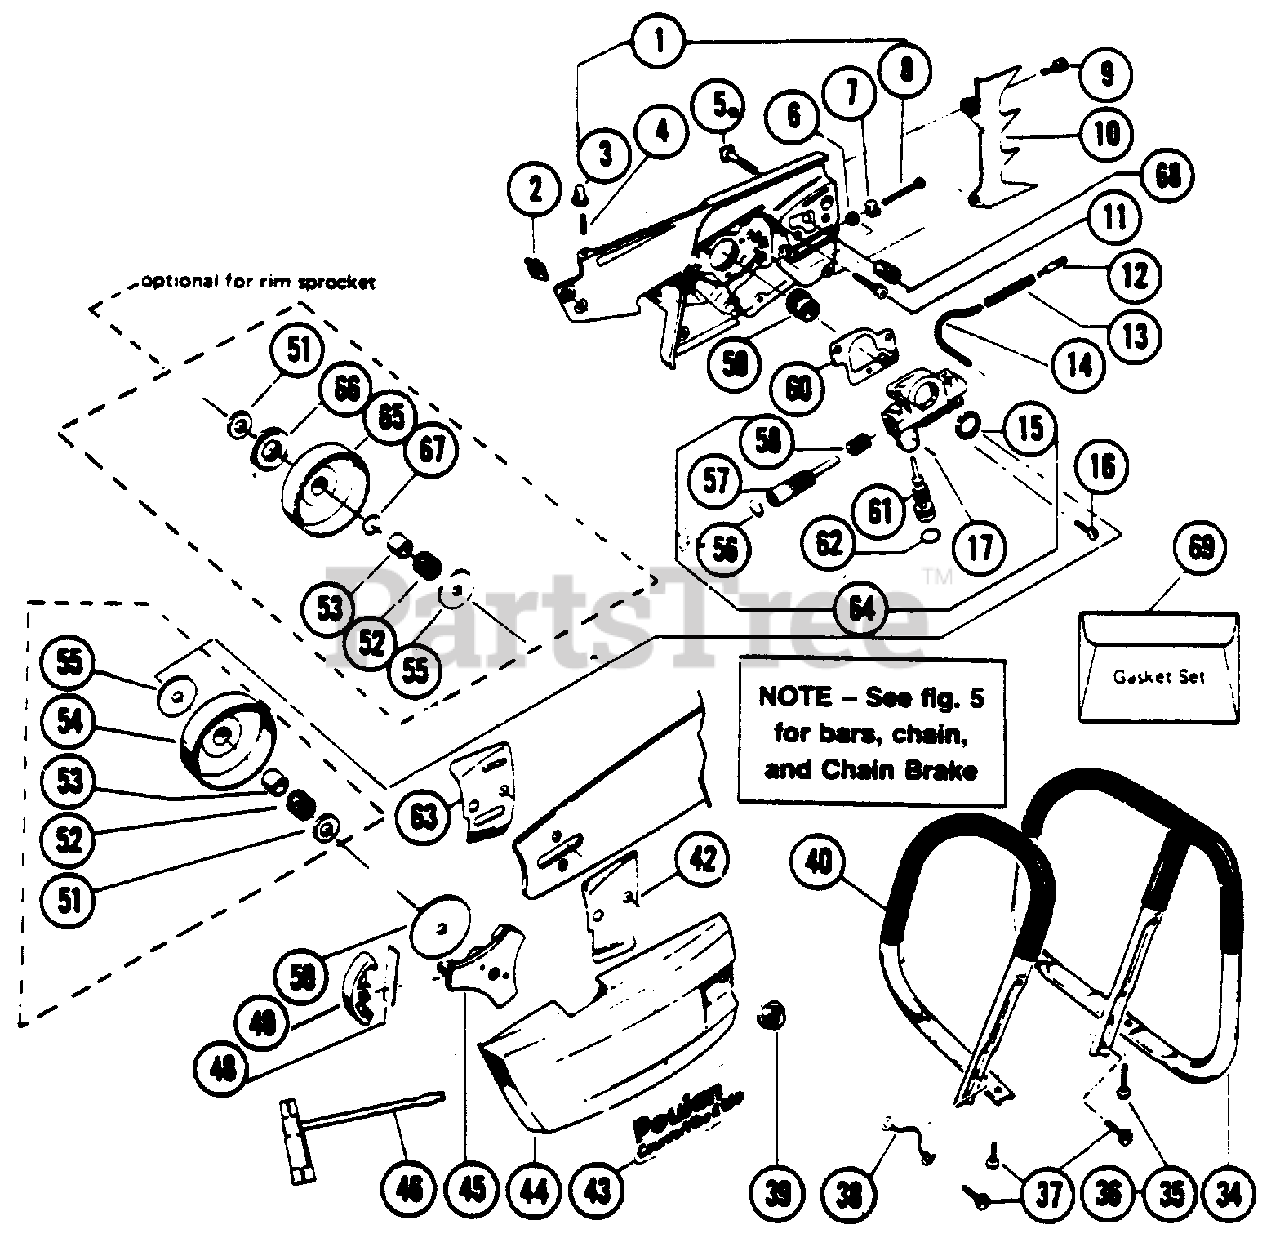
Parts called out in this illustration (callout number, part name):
1	Crankcase Ass'y. - Both Halves (includes 3, 4, 5, 6, 7, 8 & 68)
2	Bumper - Bar Clamp
3	Bushing - Cylinder Cover Mounting
4	Stud - Cylinder Cover Locating
5	Stud-Bar Mounting.
6	Nut - 10-24 Self Locking
7	Pin - Bar Adjusting
8	Screw - 10-24 x 2-3/16 Fillister Head
9	Screw - 1/4-20 x 5/8 Socket Head
11	Screw - 10-24 x 3/4 Socket Head
12	Weight & Filter - Oil Pick-up
13	Spring - Oil Line Protector
14	Line - Oil Pick-up (31/4" Long; Cut from No. 8132 Tubing)
15	Seal - Oil Pump Included in Gasket Kit 69025
16	Screw - 10-24 x 5/8
17	Pin - Adjusting Screw Stop
34	Handlebar Ass'y. - Wrap-around
35	Screw 1/4-20 x 2A x 1 1/8 (Wrap-around Handlebar)
36	Screw 1/4-20 x 3/4 (for 22142 Handlebar)
37	Screw 1/4-20 x 5/8 (Flush-cut Handlebar)
38	Wire - Ground
39	Nut - Bar Mounting (includes washer)
40	Handlebar - Flush-cut (4200)
42	Plate - Bar (outer)
43	Decal - Bar Clamp (4200)
44	Bar Clamp
45	Drive Plate - Clutch
48	Spring - Clutch Shoe (Purple)
49	Shoe - Clutch
50	Washer - Clutch shoe
51	Washer - Thrust (Black)
52	Bearing - Drum & Sprocket
53	inner Race - Clutch Drum
54	Drum & Sprocket - 7 tooth, 3/8" pitch
55	Moss Thrust Washer - Sprocket Shroud
56	Plug - Oil Pump Body
57	Plunger - Oil Pump
58	Spring - Oil Pump Plunger
59	Worm Gear
60	Gasket - Oil Pump Included in Gasket Kit 69025
61	Screw - Oil Pump Adjusting
62	O-Ring - Adjusting Screw Included in Gasket Kit 69025
63	Plate - Bar (inner)
64	Oil Pump Ass'y. (includes 15, 17, 56, 57, 58, 61 & 62)
65	Clutch Drum - Splined (optional for rim sprocket)
66	Rim Sprocket - 3/8 pitch, 7 tooth (optional)
67	Spacer - Inner Race (optional for rim sprocket)
68	Vent Plug - Oil Tank
69	Gasket Kit
